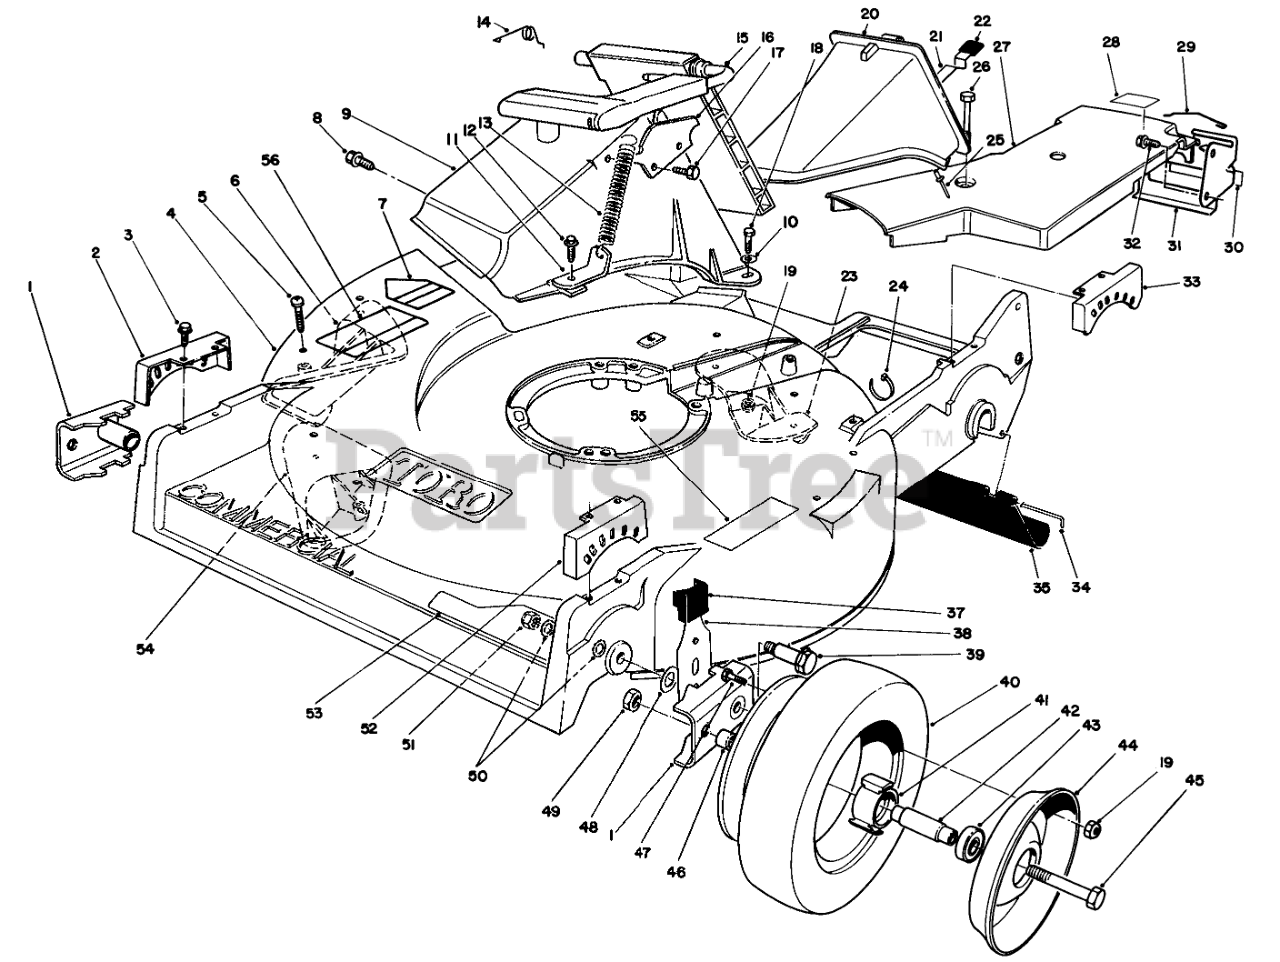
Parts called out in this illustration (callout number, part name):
1	ARM-PIVOT, FRONT
2	QUADRANT-FRONT, RH
3	SCREW-HWHTF
4	Housing-Commercial (Incl. Ref. #7, 53, & 55)
5	SCREW-PPH
6	KICKER-RH
7	DECAL-DANGER
8	SCREW AND WASHER ASM
9	DISCHARGE TUNNEL
10	WASHER-FLAT
11	BRACKET-SPRING
12	SCREW-HWH
13	SPRING-DOOR
14	RETAINER-DOOR
15	DOOR ASSEMBLY
16	DOOR LATCH PLATE
17	SCREW-PLASTITE
18	SCREW-HH
19	NUT-LOCK, NI
20	Plug-Discharge (Incl. Ref. #21, 22, & 25)
21	LATCH-PLUG, DISCHARGE
22	GRIP-LATCH
23	KICKER-REAR
24	TIE-CABLE
25	RIVET-HEAD, FLAT
26	SCREW-HHFTF
27	COVER-BELT
28	LABEL-GREASE
29	RETAINER-CABLE
30	DECAL-POSITION, GEAR
31	BRACKET-ADJUSTMENT, TRACTION
32	SCREW-HWHTF
33	QUADRANT-REAR, LH
34	ROD-SHIELD
35	SHIELD-TRAILING
37	KNOB-ARM
38	FRONT SPRING ARM ASM
39	BOLT-WHEEL
41	HUB-BEARING
42	SPACER-BEARING
43	BEARING-WHEEL
44	Wheel-Half
45	SCREW-HH
46	SPACER-WHEEL
47	SCREW-HH
48	WASHER-THRUST
49	NUT-LOCK, CONE
50	WASHER
51	NUT-LOCK
52	QUADRANT-FRONT, LH
53	DECAL - RECYCLER
54	KICKER-FRONT
55	DECAL-INSTRUCTION, SAFETY
56	DECAL - DANGER, COVERS
